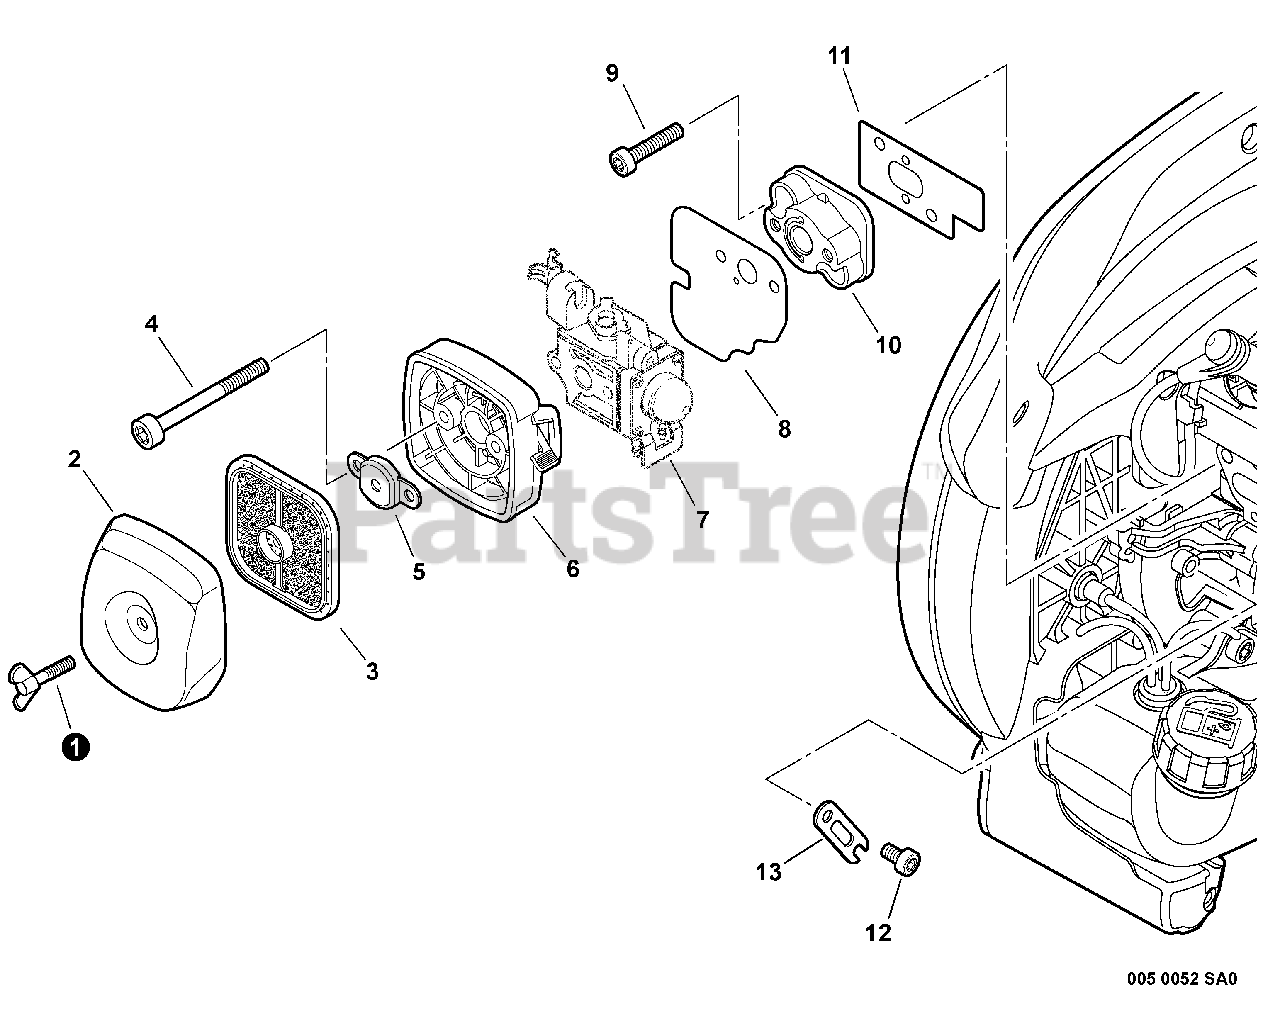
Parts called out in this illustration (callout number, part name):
1	THUMBSCREW
2	COVER, AIR FILTER - BLACK
3	FILTER, AIR - DOUBLE LAYER
4	SCREW - 5X65
5	PLATE, PREVENT
6	CASE, AIR FILTER - BLACK
7	CARBURETOR
8	GASKET, INTAKE
9	SCREW - 5X25
10	INSULATOR, INTAKE
11	GASKET, INTAKE
12	SCREW - 5X8
